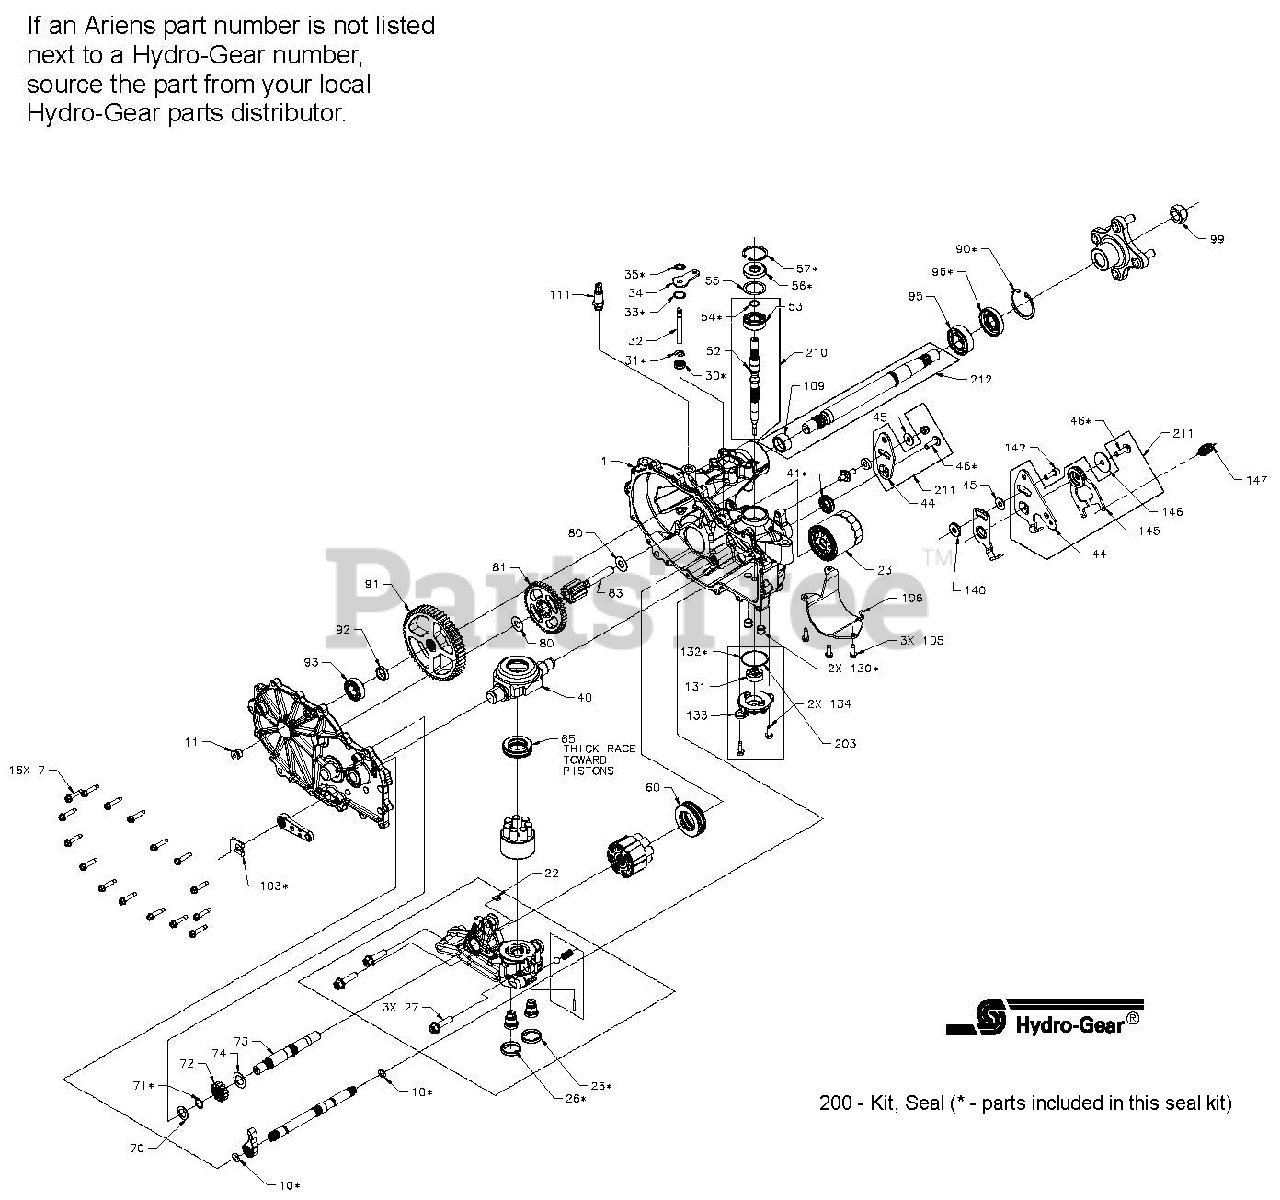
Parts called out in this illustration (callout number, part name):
1	Kit, Main Housing LH
7	HFHCS 1/4-20 X 1.25"
11	PLUG, STEEL (WITH SEAL)
22	PLATE, BYPASS
23	Filter, Oil
30	SEAL, LIP .375X.75X.25
31	RING. RETAINING
32	Rod, Bypass
33	RING, RET .750
34	Arm, Bypass
35	RING, RTNG .
40	TRUNNION, SWASHPLATE
45	WASHER
46	TWHCS 5/16-24 X 1.00
52	Shaft, Input
53	BRG, BALL 17X40X12
54	Ring, Ret Wire .561 ID
55	WASHER 1.23X1.56X.04
56	SEAL, LIP 17X40X7
57	RING, RET 1.56 INT
60	Bearing, Thrust
65	BEARING. THRUST 30 X 52 X 13
70	WASHER .63X1.0X.05
71	RING, RET 62 EXT
72	Gear, 13T, Steel
73	Shaft, Motor
74	WASHER .71 X 1.16 X .04
80	WASHER .5X1.0X.032
83	JACK SHAFT (PIN)
90	RING, RETAINING
95	BEARING, BALL 25.4 X 52 X 15
96	SEAL, LIP
99	NUT, HEX, LOCK 3/4-16
103	Clip, Retaining
105	HFHCS 1/4-20X.75
106	Guard, Filter, LH
111	Fitting, Str 9/16-18 SAE .5 Barb
130	Tube, Connecting
131	GEROTOR
133	Cover, Charge Pump
134	HFHCS 1/4-20X.75
142	SHCS 5/16-24X1 PATCH
146	WASHER
147	Spring, Extension Rtn - 34 lbs
200	Kit, Seal ( * - parts included in this kit)
NS	SEALANT TUBE 10.1OZ.
NS	20W50 Oil
